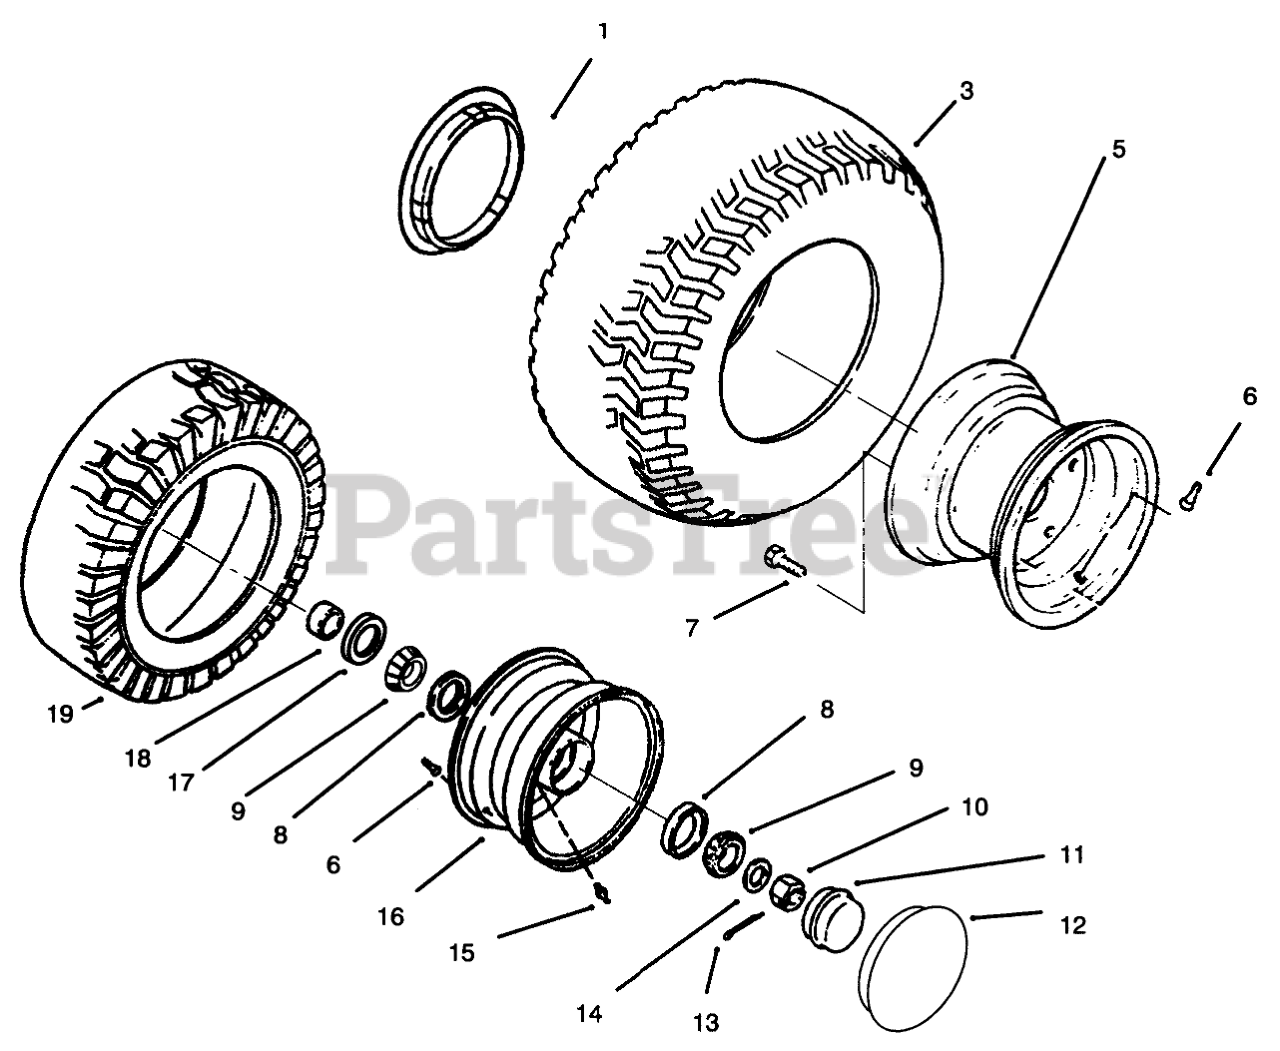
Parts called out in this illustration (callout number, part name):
1	12"-HUB CAP LOGO
3	TIRE 23 X 10.50-12
5	RIM ASM
6	VALVE
7	BOLT-LUG
8	Cup
9	Bearing
10	NUT-HEX, SLOTTED
11	DUST CAP
12	8"-HUB CAP LOGO
13	PIN-COTTER
14	WASHER
15	ZERK-GREASE
16	Wheel-Front (Incl. Item 15 & Qty. 2 of Item 8)
17	SEAL-OIL
18	SPACER
19	TIRE-16 X 7.50 TURF
